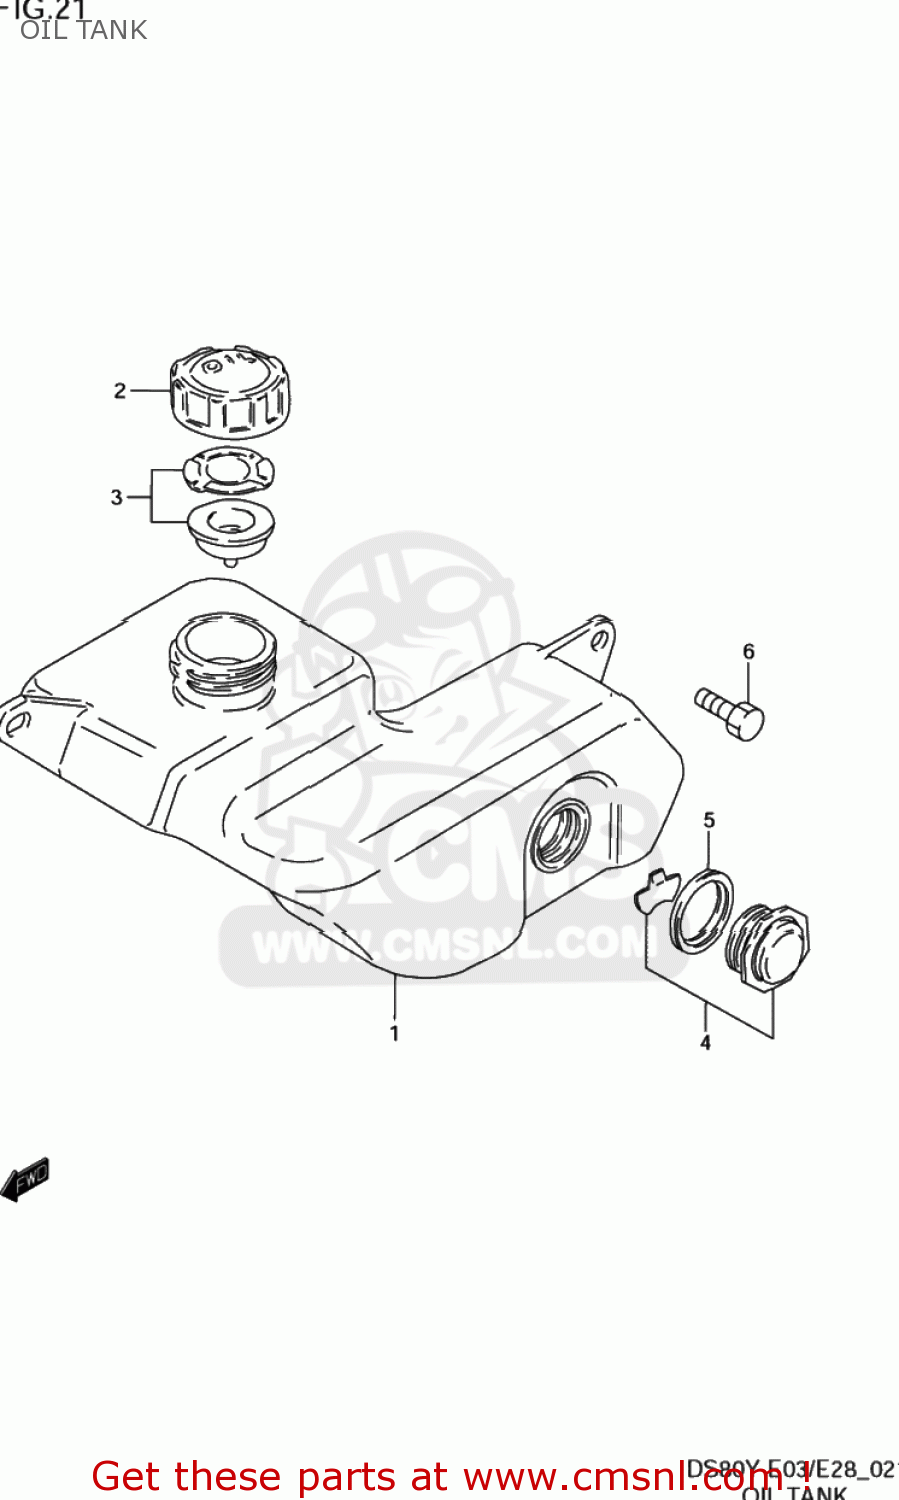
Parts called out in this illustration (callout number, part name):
1	TANK,OIL
2	CAP,OIL TANK
3	GASKET SET (NAS)
4	LENS SET,OIL LEVEL
5	GASKET (NAS)
6	BOLT(6X16)
